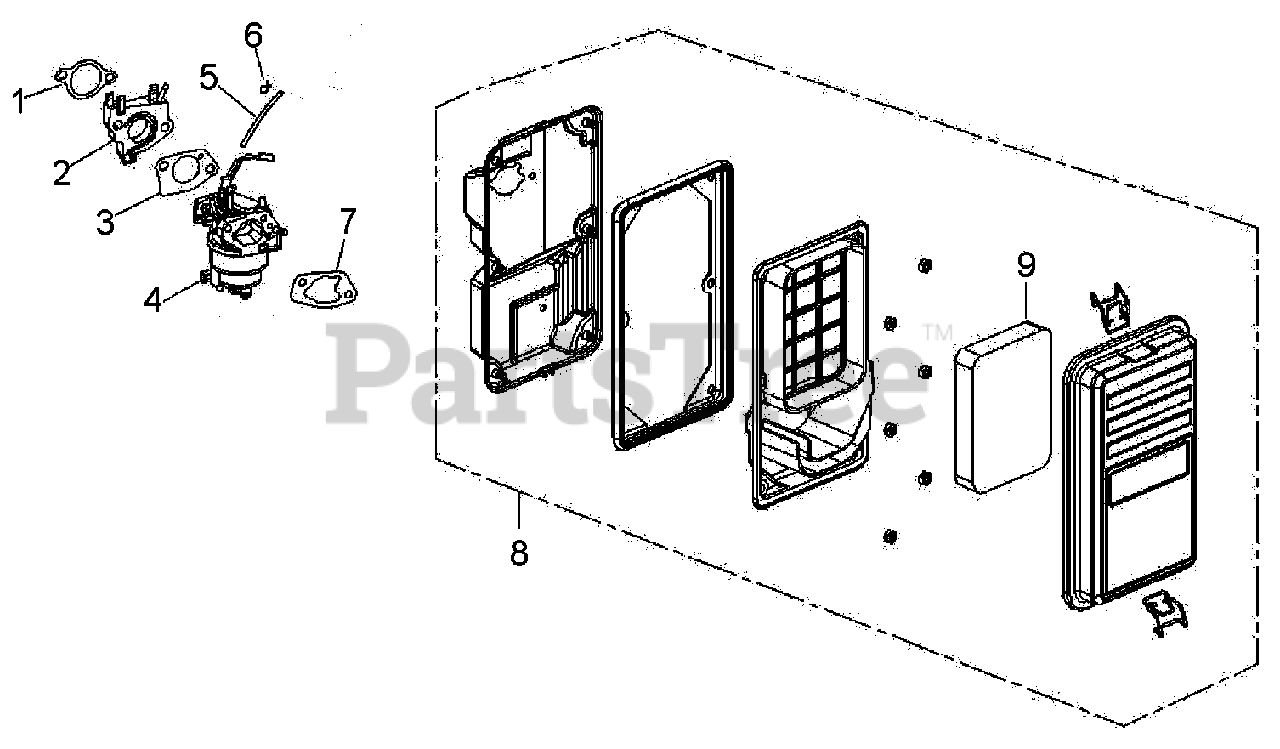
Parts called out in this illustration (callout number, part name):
1	GASKET, CARBURETOR
2	SPACER, CARBURETOR
3	GASKET, CARBURETOR
4	CARBURETOR ASSY.
5	TUBE, FUEL
7	GASKET, CARBURETOR
8	AIR CLEANER ASSY.
9	ELEMENT, AIR CLEANER
